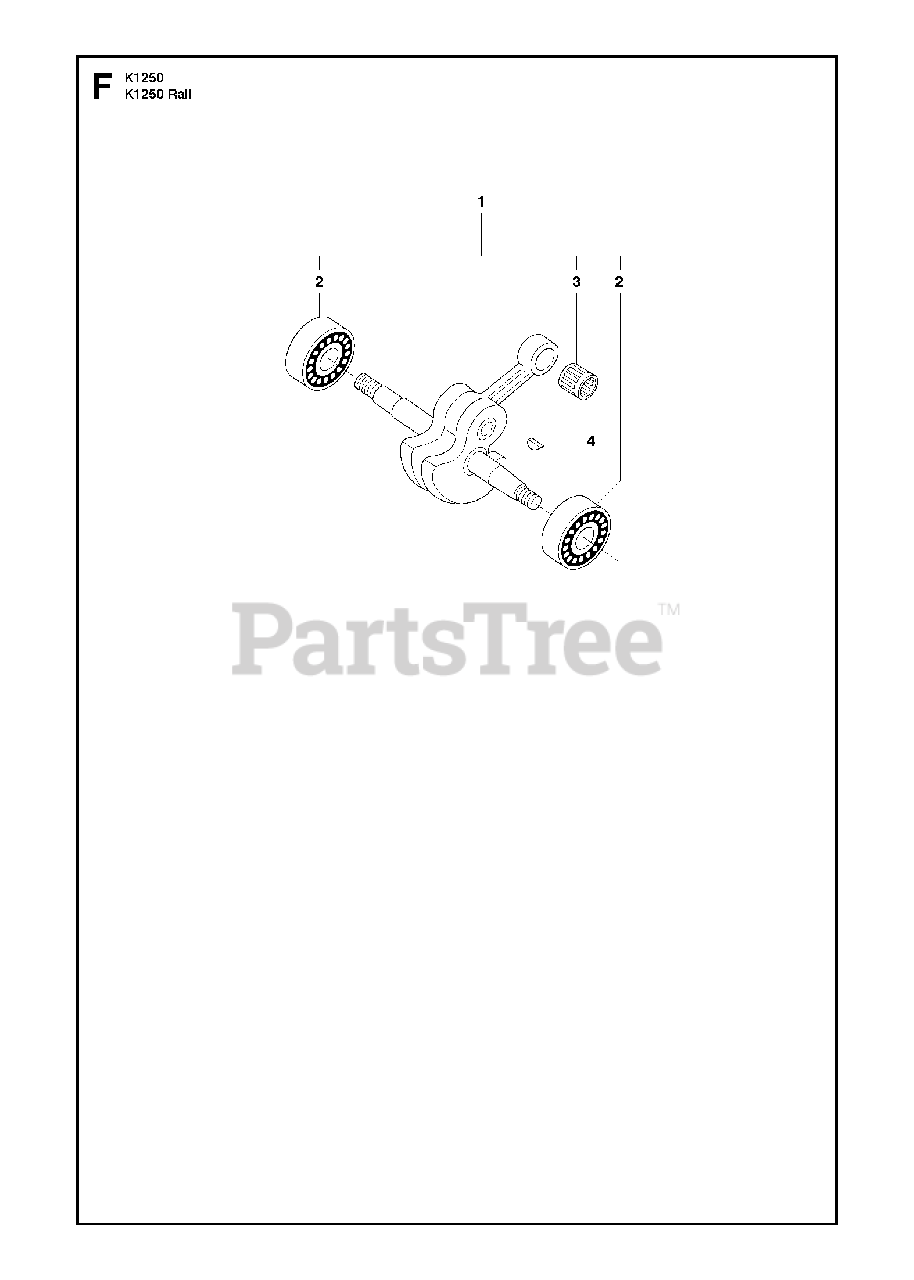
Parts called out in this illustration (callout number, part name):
1	CRANKSHAFT ASSYIncl. 2, 3
2	BALL BEARING
3	NEEDLE HOLDER
4	WOODRUFF KEY
